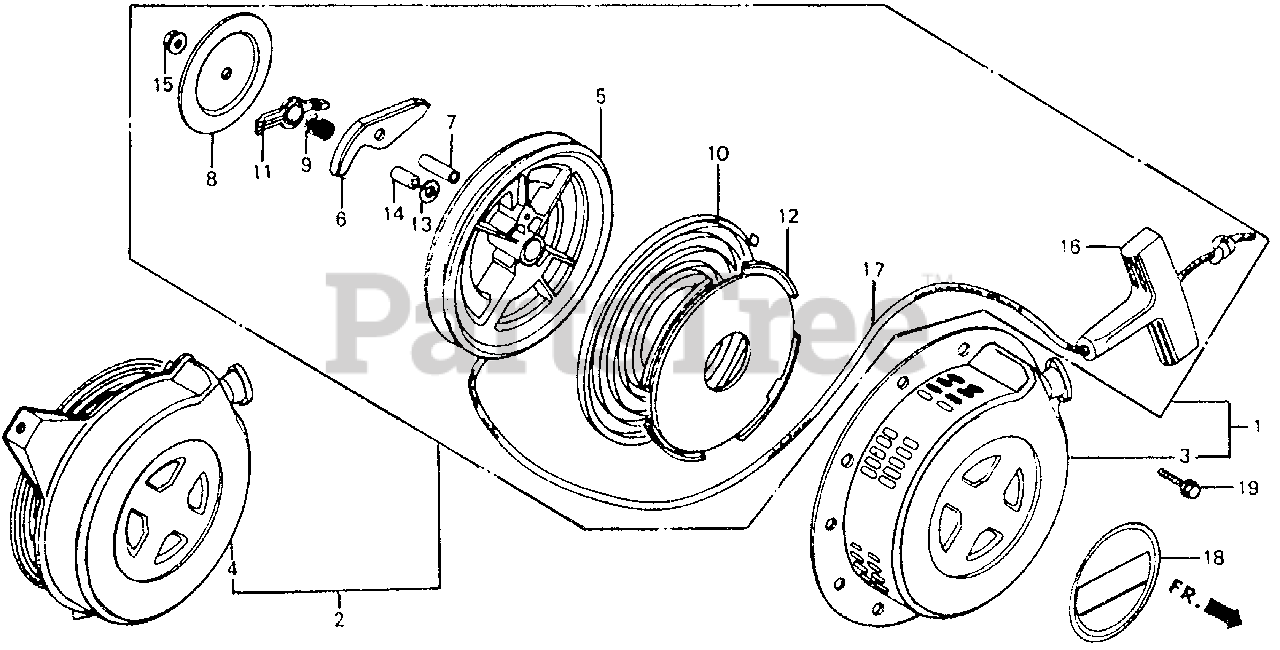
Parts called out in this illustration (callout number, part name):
2	STARTER ASSY., RECOIL *R8* (BRIGHT RED)
4	CASE, RECOIL STARTER *R8* (BRIGHT RED)
5	PULLEY, RECOIL STARTER
6	RATCHET, STARTER
7	PIN, STARTER RATCHET
8	PLATE, FRICTION
9	SPRING, FRICTION
10	SPRING, RECOIL STARTER
11	GUIDE, RATCHET
12	CASE, RECOIL STARTER SPRING
13	WASHER, STARTER
14	SHAFT, SUB
15	NUT
16	KNOB, RECOIL STARTER
17	ROPE, RECOIL STARTER (#5X59") (NA USE ALT:08550-ZG921-11)
18	EMBLEM (EXTERNAL)
19	BOLT, FLANGE (6X8)
19	BOLT, FLANGE (6X10)
